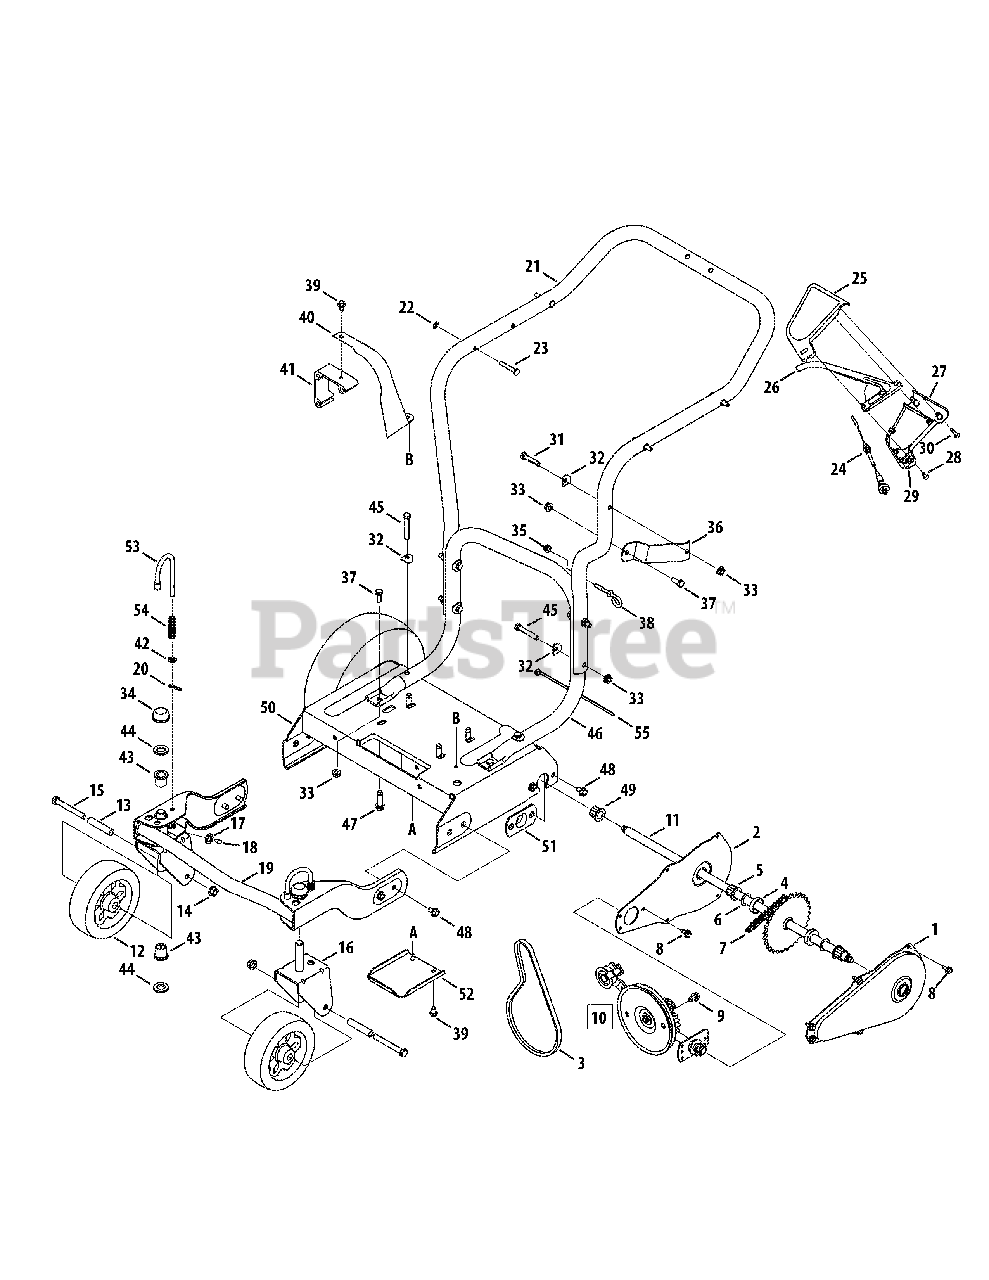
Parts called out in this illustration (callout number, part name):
1	Chain Case - LH
2	Chain Case - RH
5	Hex Flange Bearing
6	Flat Washer
8	TT Screw, 1/4-14 x 0.625"
9	Hex Washer Screw, 5/16
10	Chipper Shredder Trans. Ass’y.
11	Axle Assembly
12	Wheel, 6.0 x 2.0
14	Flange Lock Nut, 3/8-16
15	Hex Cap Screw, 3/8-16 x 3.0
16	Bracket Assembly
17	Flat Washer, .203 ID x.403 OD
18	Grease Fitting, 3/16
19	Bracket Assembly
20	Cotter Pin
23	Stud Pin, .250 x 1.75
24	Clutch Cable - 56"
25	Upper Clutch Cover
26	Drive Lever
27	Lower Clutch Cover
28	Screw, #10-12 x.750
29	Mounting Cable Cap
30	Screw, #10-16 x 1.25
31	Hex Cap Screw, 5/16-18 x 1.50
32	Shoulder Washer, .320 ID x.93 OD
33	Hex Flange Lock Nut, 5/16-18
35	Hex Nut, 1/4-28
36	Discharge Chute Bracket
37	Hex Cap Screw, 5/16-18 x.75
39	Hex Washer Screw, 1/4-14 x.625
40	Belt Cover
41	Engine Mounting Adapter
42	Flat Washer, .330 ID x.630 OD
43	Flange Bearing, .632 ID
44	Flat Washer, 5/8 ID x 1.0 OD
45	Hex Cap Screw, 5/16-18 x 1.75
46	Lower Push Handle
47	Screw, 3/8-16 x 1.25
48	Hex Washer Screw, 5/16-18 x.625
49	Hex Flange Bearing, .631 x.720
50	Frame Assembly
52	Transmission Cover
54	Compression Spring
55	Cable Tie
